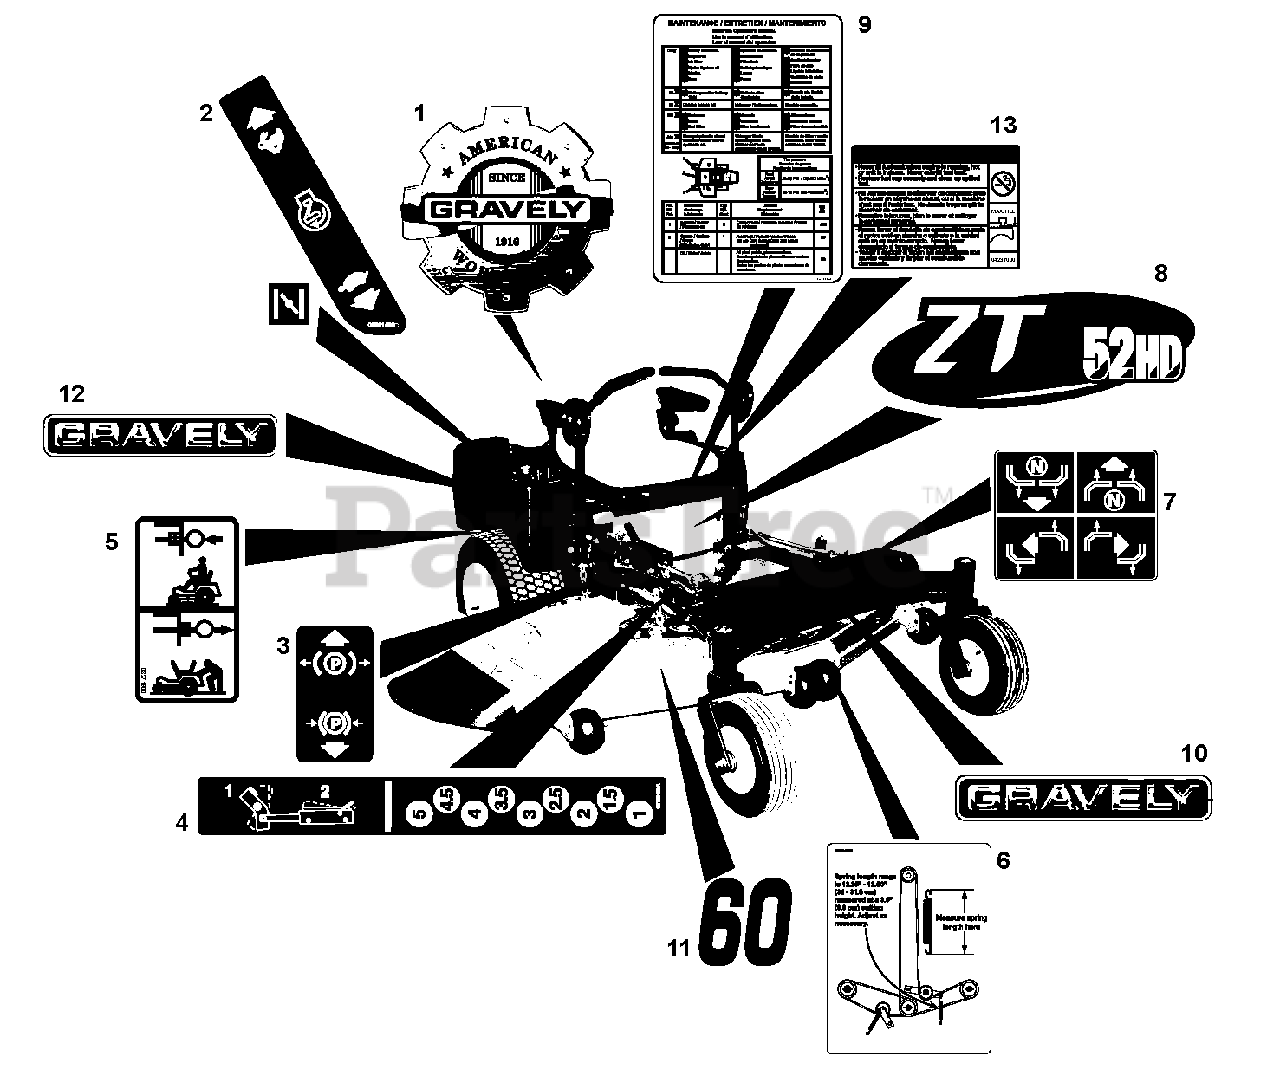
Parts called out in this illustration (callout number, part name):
1	Decal, Gravely Heritage Small
2	Decal, Control
3	Decal, Parking Brake Lever
4	Decal, Height of Cut
5	Decal, Transmission Disconnect
6	Decal, Belt Diagram
7	Decal, Instructional Steering
8	Decal, 44 HD (991090, 098)
8	Decal, 48 HD (991082, 099)
8	Decal, 52 HD (991083, 100)
8	Decal, 60 HD (991084, 091, 101)
9	Decal, Maintenance Instructions
10	Decal, 15" Gravely Logo
11	Decal, 60" (991084, 091, 101)
11	Decal, 52" (991083, 100)
11	Decal, 48" (991082, 099)
11	Decal, 44" (991090, 098)
12	Decal, Fuel Tank Gravely
13	Decal, Fuel Warning
